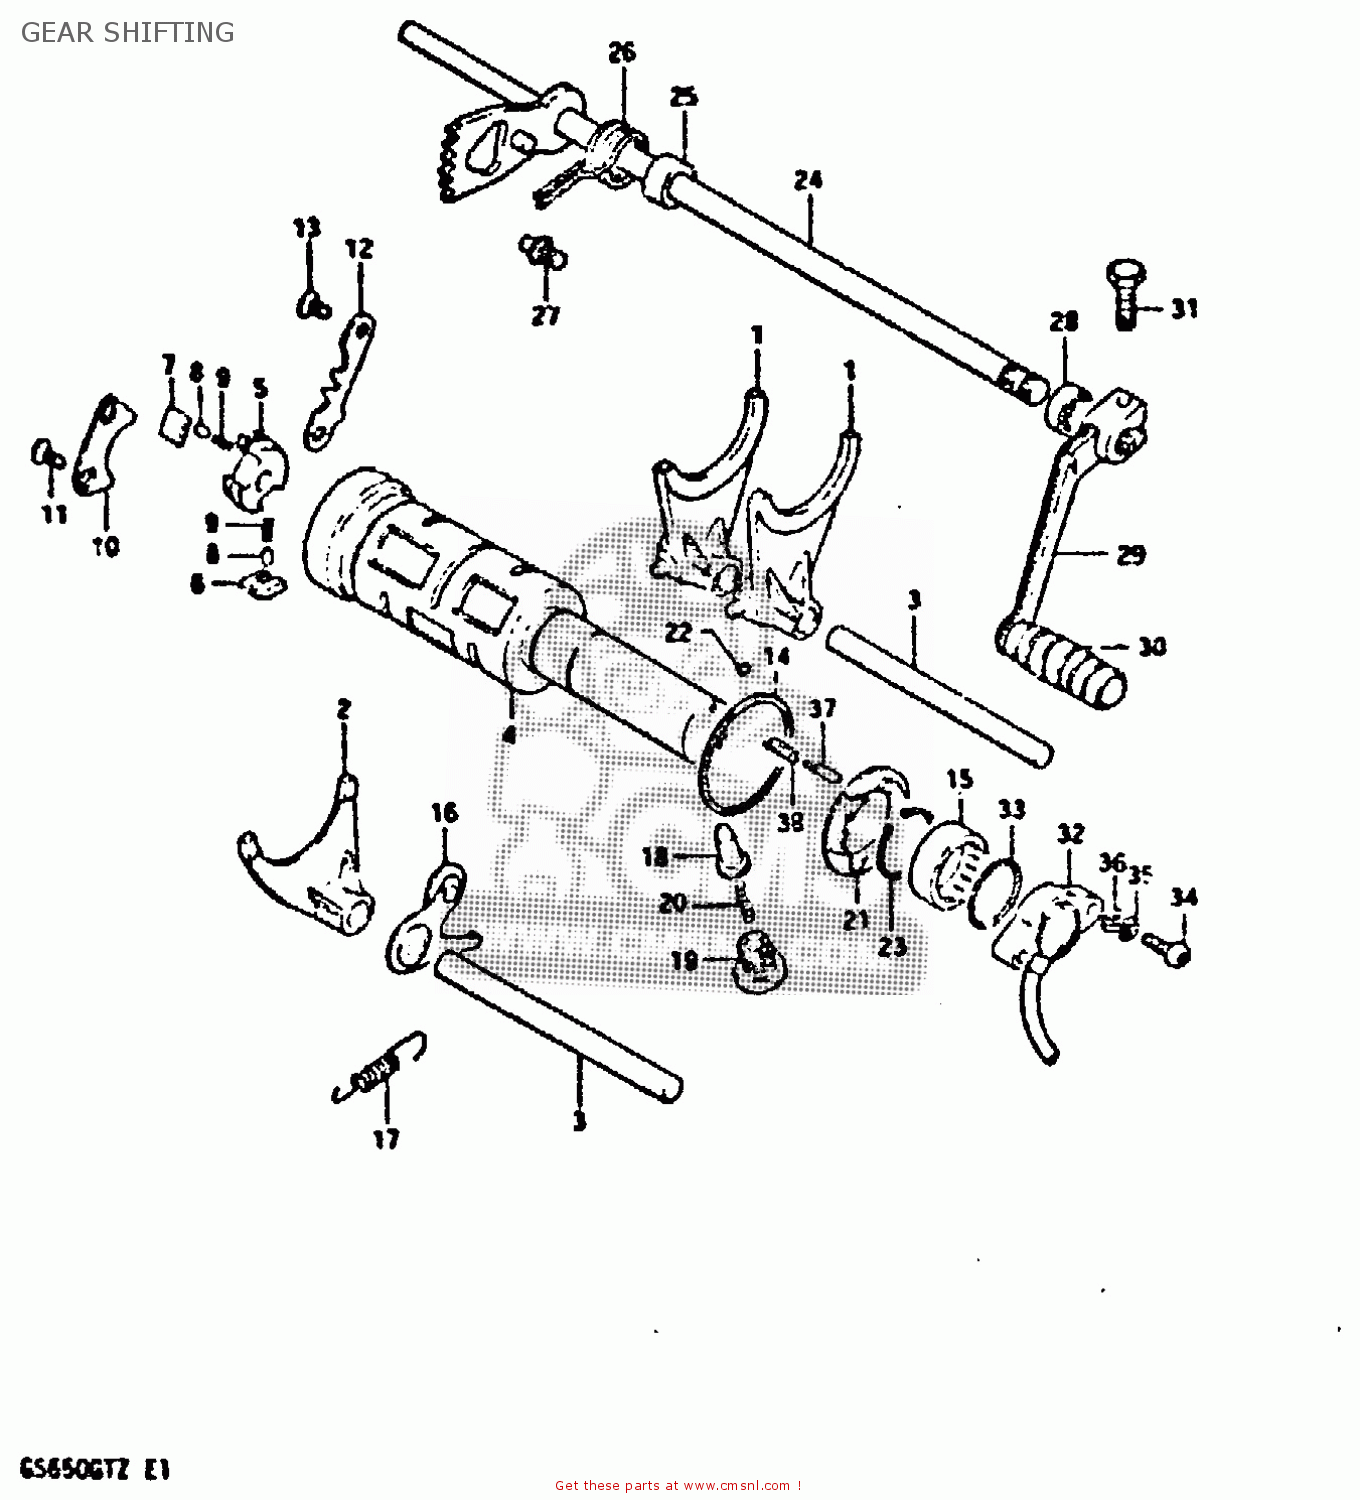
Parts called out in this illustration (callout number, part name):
1	FORK,GEAR SHIFT NO.1
2	FORK,GEAR SHIFT NO.3
3	SHAFT,GEAR SHIFT FORK
4	CAM,GEAR SHIFT
5	SHIFTER,GEAR SHIFT CAM
6	PAWL,GEAR SHIFT NO.1
7	PAWL,GEAR SHIFT NO.2
8	PIN(5X8)
9	SPRING
10	LIFTER,GEAR SHIFT PAWL
11	SCREW
12	GUIDE,GEAR SHIFT
13	SCREW
14	WASHER(40X45X1)
15	BEARING
16	STOPPER,GEAR SHIFTING
17	SPRING
18	STOPPER,GEAR SHIFT CAM NO.2
19	HOLDER,GEAR SHIFT CAM STOP SPR
20	SPRING
21	PLATE,GEAR SHIFT CAM STOPPER
22	PIN 4X6
23	CIRCLIP
24	SHAFT,GEAR SHIFT
25	SPACER(12X20X15.3)
26	SPRING
27	STOPPER,GEAR SHIFT CAM
28	OIL SEAL
29	LEVER ASSEMBLY,GEAR SHIFTING
30	COVER
31	BOLT
32	BASE ASSEMBLY,NEUTRAL SWITCH TERMINAL
33	O-RING (D:2.4 ID:26.2)
34	SCREW 5X20
35	LOCK WASHER
36	WASHER
37	PIN(5X15.5)
38	SPRING
